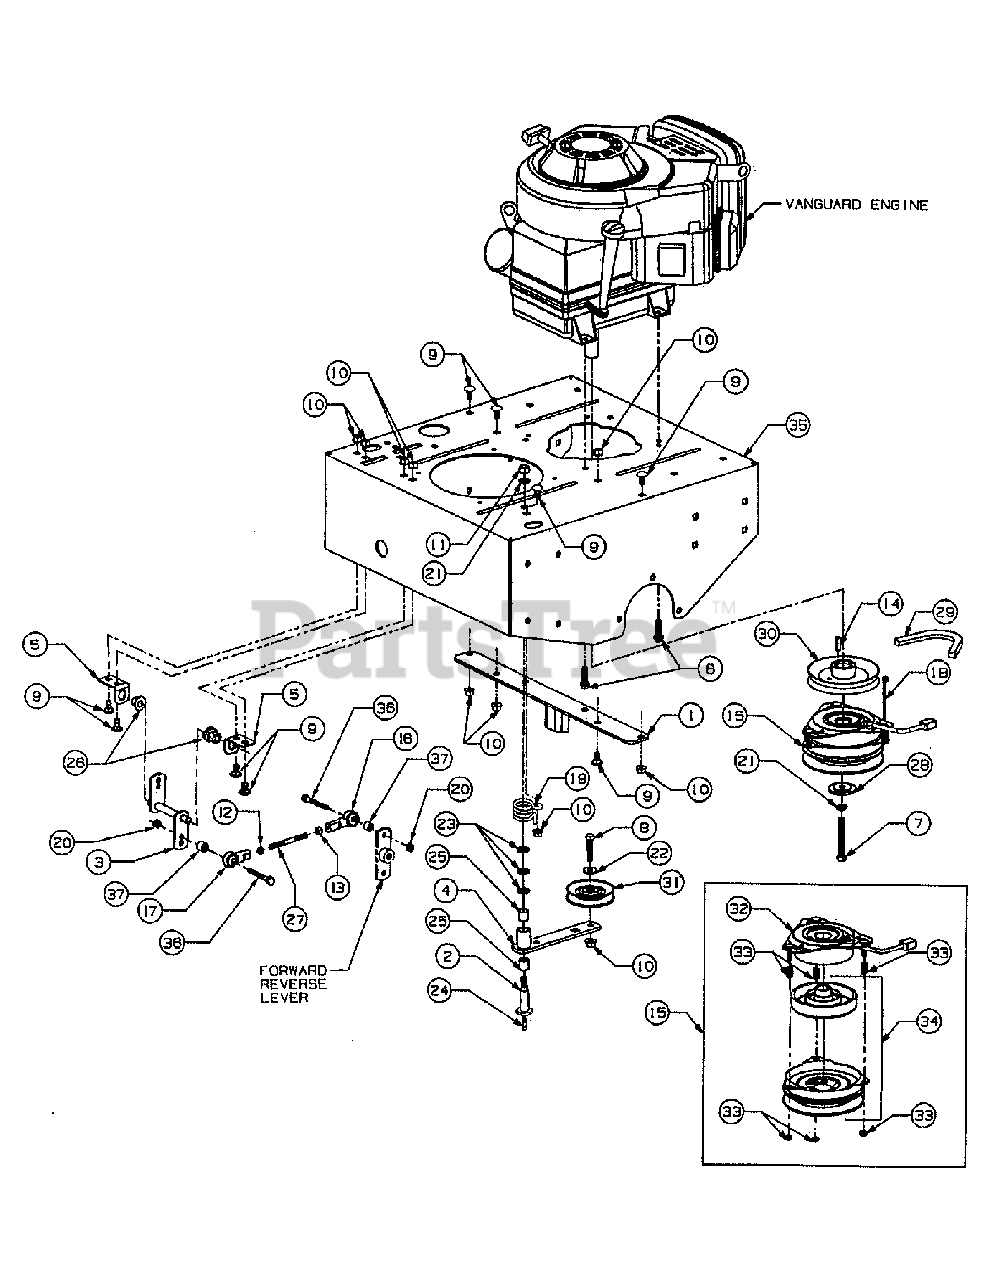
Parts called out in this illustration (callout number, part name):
3	Lever, F/R Control
4	Arm, Assembly, Idler
5	Bracket, Lever Angle
6	Screw, Hex L-Wash Tapp, 3/8-16 x 1.25
7	Screw, Hex Cap, 7/16-20 x 3.0 Gr 5
8	Screw, Hex Cap, 3/8-16 x 1.75
9	Bolt, Sht Nk Carriage, 3/8-16 x .75 Gr 5
10	Nut, Hex Flanged Lock, 3/8-16
11	Nut, Hex, 7/16-14 Gr 5
12	Nut, Hex Jam, 5/16-24 LH Thread
13	Nut, Hex, 5/16-24 Gr 5
14	Key Square, 1/4 x 1.0
15	Clutch Assembly, PTO
16	Rod End, Spherical, 5/16-24
17	Rod End, Spherical, 5/16-24, LH Thread
18	Cable Tie
19	Spring, Torsion
20	Nut, Hex Flange Lock, 5/16-18 Gr 5
21	Washer, Lock 7/16
22	Washer, Special, .378 x 1.00 x .125 Thk
23	Washer, Flat, .469 x .875 x .105 Thk
24	Fitting, Lube
25	Bearing, Sleeve
26	Bearing, Hex Flange
27	Rod, Control
28	Spacer, Clutch
29	Belt, Transmission, 1/2 x 40.0
30	Pulley, Engine
31	Pulley, V-Idler
32	Field Assembly
33	Mouting Accessories
34	Kit, Armature & Rotor
35	Deck w.Graphic, Engine Mtg
35	Graphic, Warning
36	Screw, Hex Cap, 5/16-18 x 1.38 Gr 5
37	Spacer, .317 ID x .625 OD x .343
